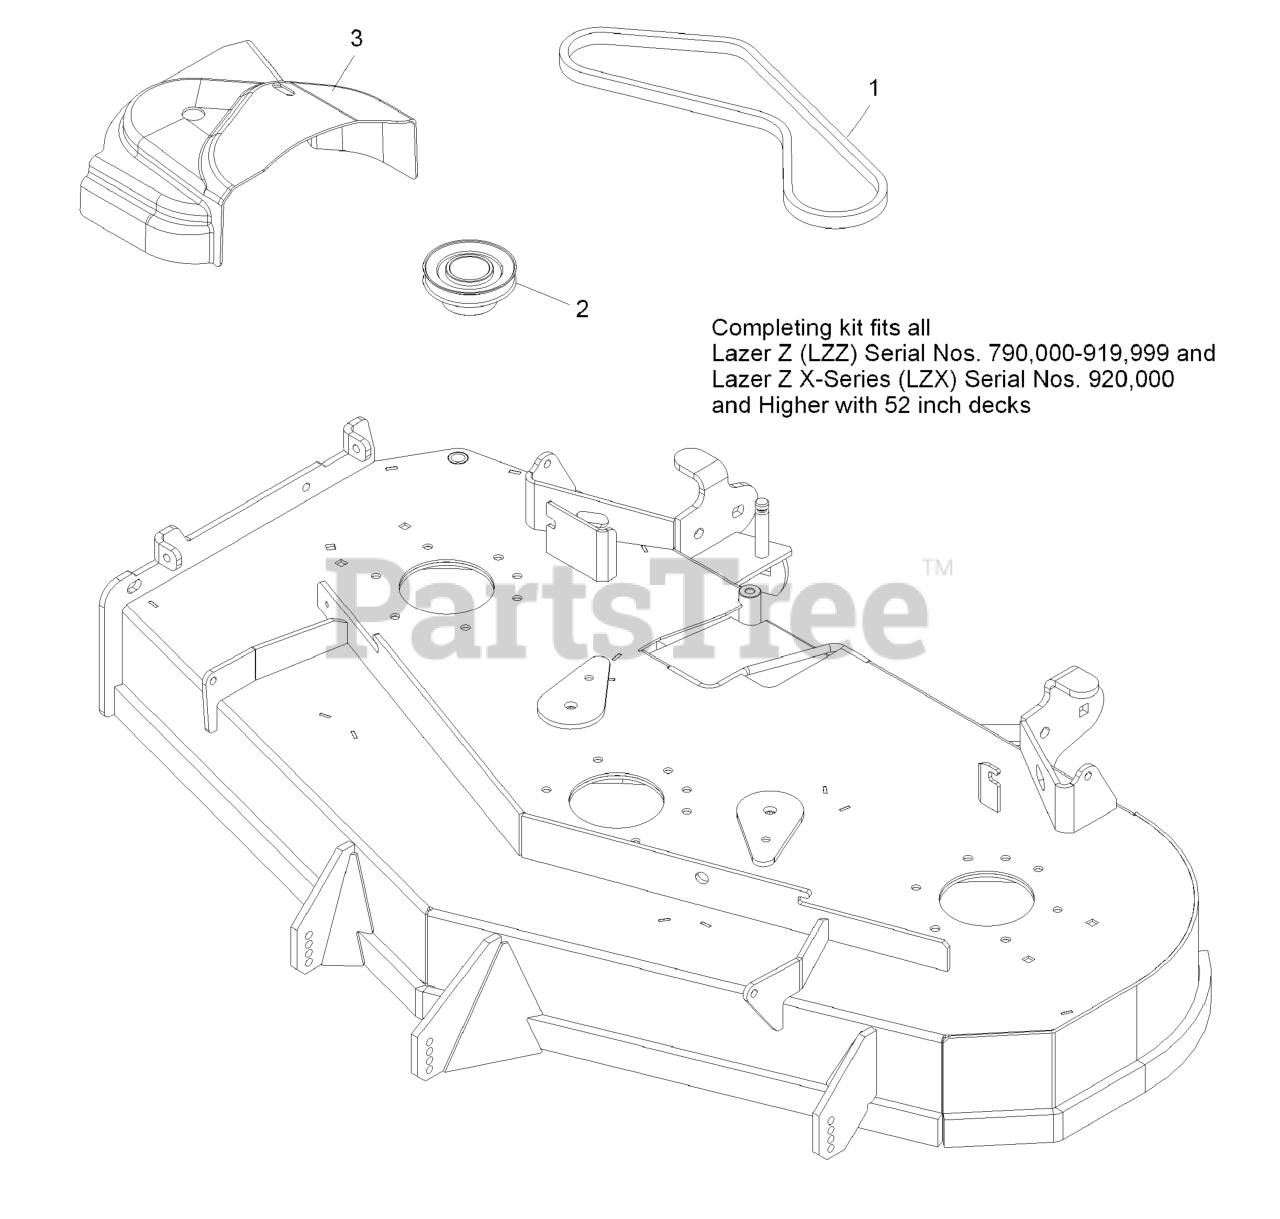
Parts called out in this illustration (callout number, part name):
1	BELT, BLOWER 52"DECK
2	SHEAVE,DRIVE LZUV 526
3	COVER,BELT UV 52
